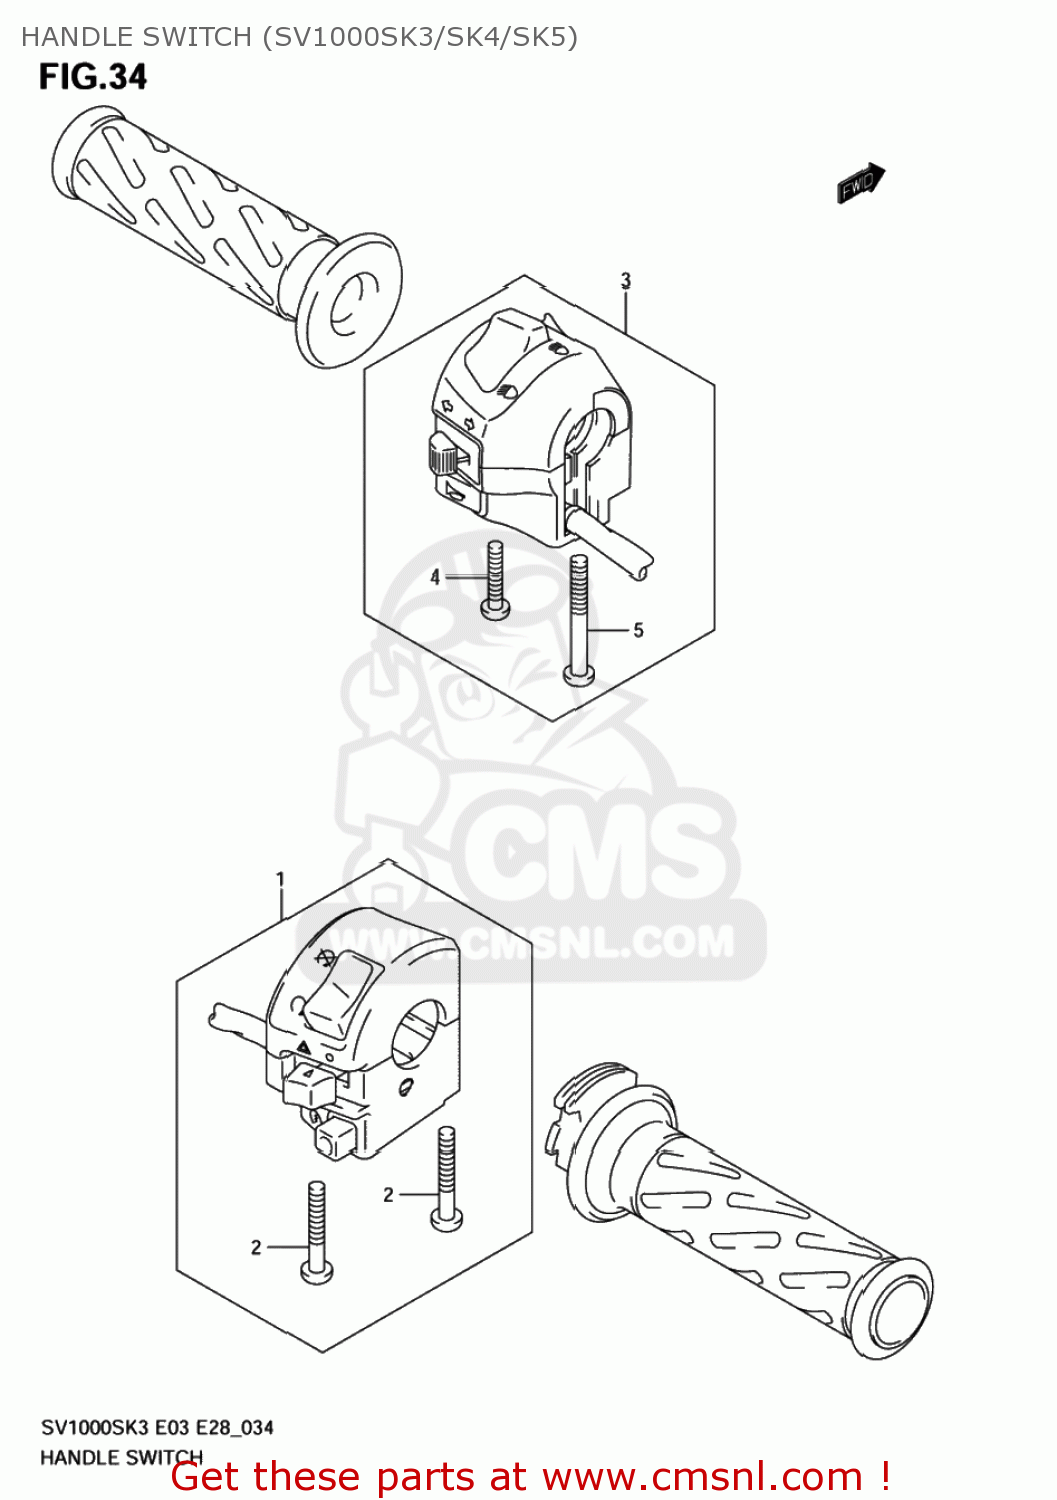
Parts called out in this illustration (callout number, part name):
1	SWITCH ASSY,HANDLE,R
2	SCREW
3	SWITCH ASSY,HANDLE,L
4	SCREW
5	SCREW
